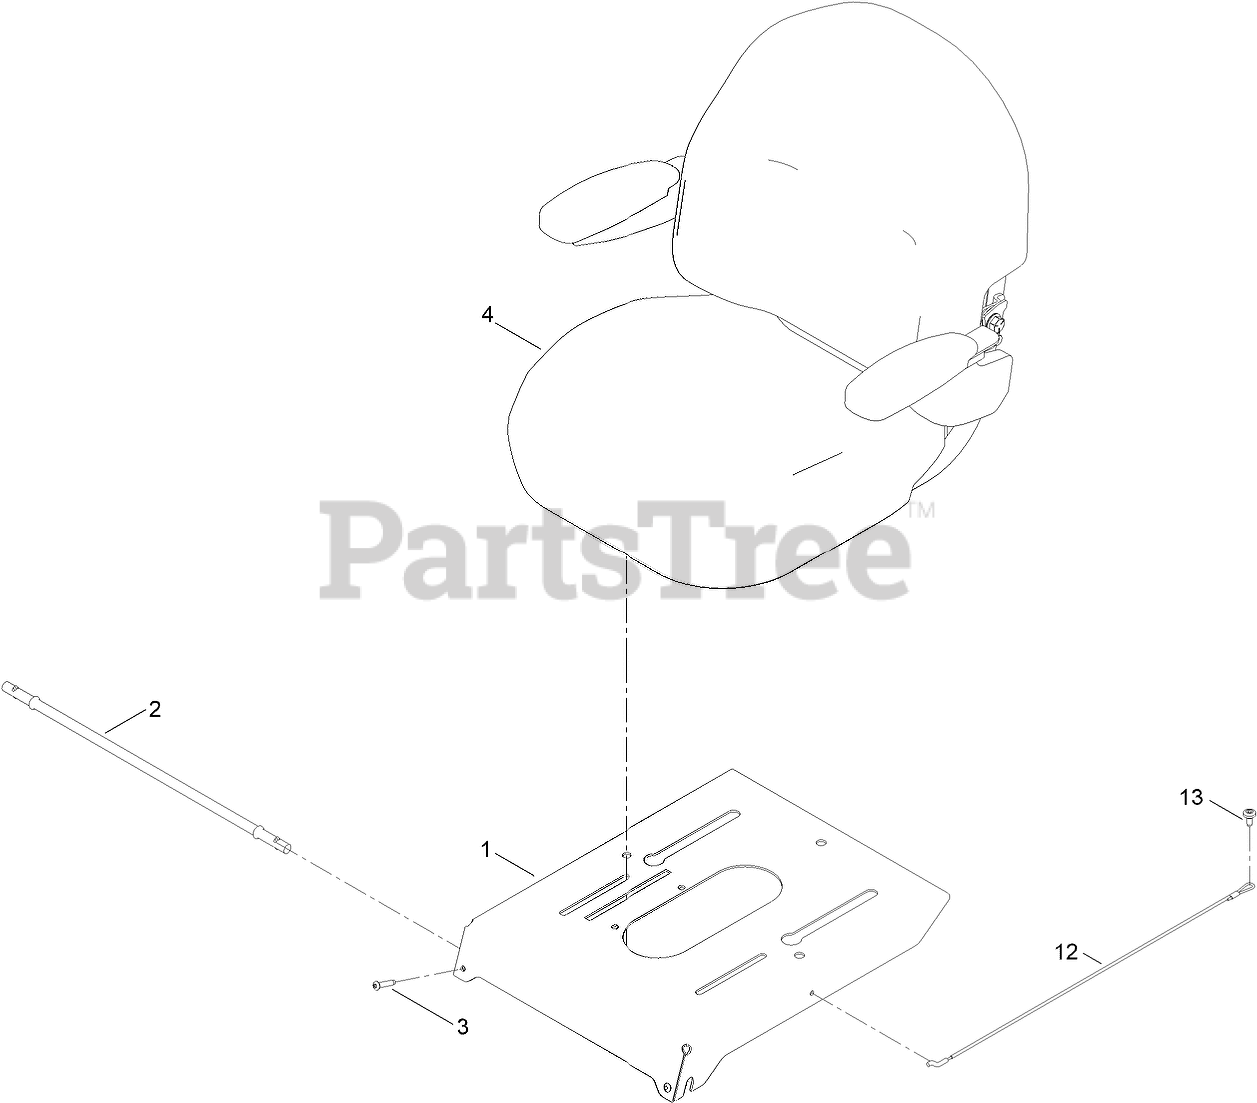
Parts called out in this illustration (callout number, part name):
1	PAN-SEAT, DELUXE
2	ROD-PIVOT
3	SCREW-TTH, THREAD ROLLING
4	SEAT ASM
12	CABLE-LANYARD
13	SCREW-SHOULDER
